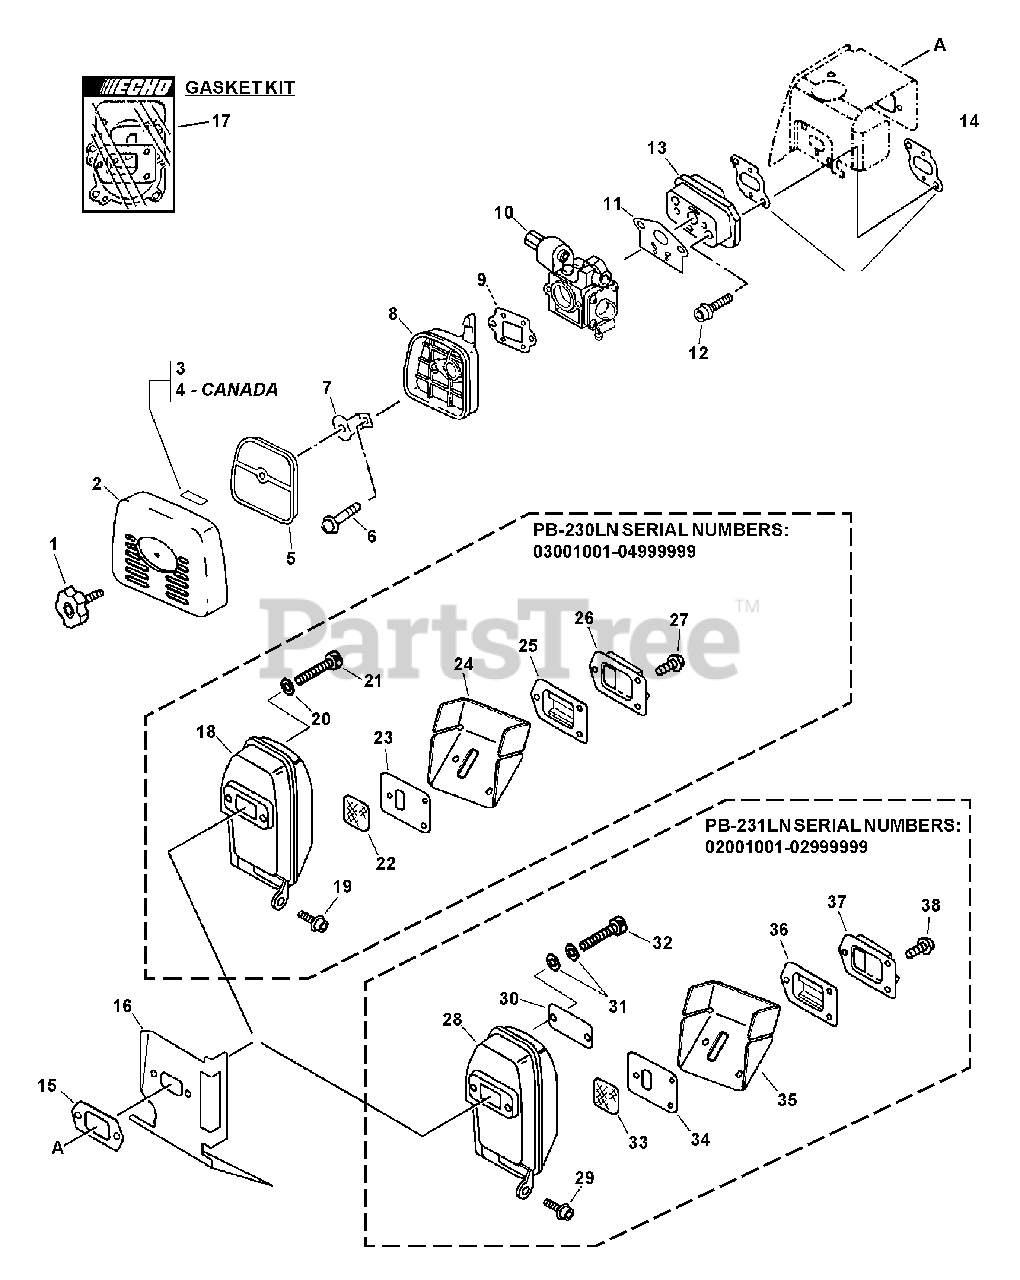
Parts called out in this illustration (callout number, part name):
1	THUMBSCREW
2	COVER, AIR FILTER
3	LABEL, CHOKE
4	LABEL, CHOKE
5	FILTER, HEAVY-DUTY AIR
6	SCREW 5×60
7	PLATE, PREVENT
8	CASE, AIR FILTER
9	SPACER
10	CARBURETOR - RB-K60A
11	GASKET, CARBURETOR
12	BOLT 5×25
13	INSULATOR, INTAKE
14	GASKET, INTAKE
15	GASKET, EXHAUST
16	SHIELD, EXHAUST
17	GASKET KIT
18	MUFFLER
19	BOLT 5×16
20	WASHER, FLAT 5.5×10×0.8
21	BOLT 5×60
22	SCREEN, SPARK ARRESTER
23	GASKET, EXHAUST
24	GASKET, EXHAUST
25	GUIDE, EXHAUST
26	GUIDE, EXHAUST
27	SCREW 4×12
28	MUFFLER
29	BOLT 5×16
30	PLATE, EYE
31	CONICAL WASHER
32	BOLT M5×65
33	SCREEN, SPARK ARRESTER
34	GASKET, EXHAUST
35	GASKET, EXHAUST
36	GUIDE, EXHAUST
37	GUIDE, EXHAUST
38	SCREW 4×12
